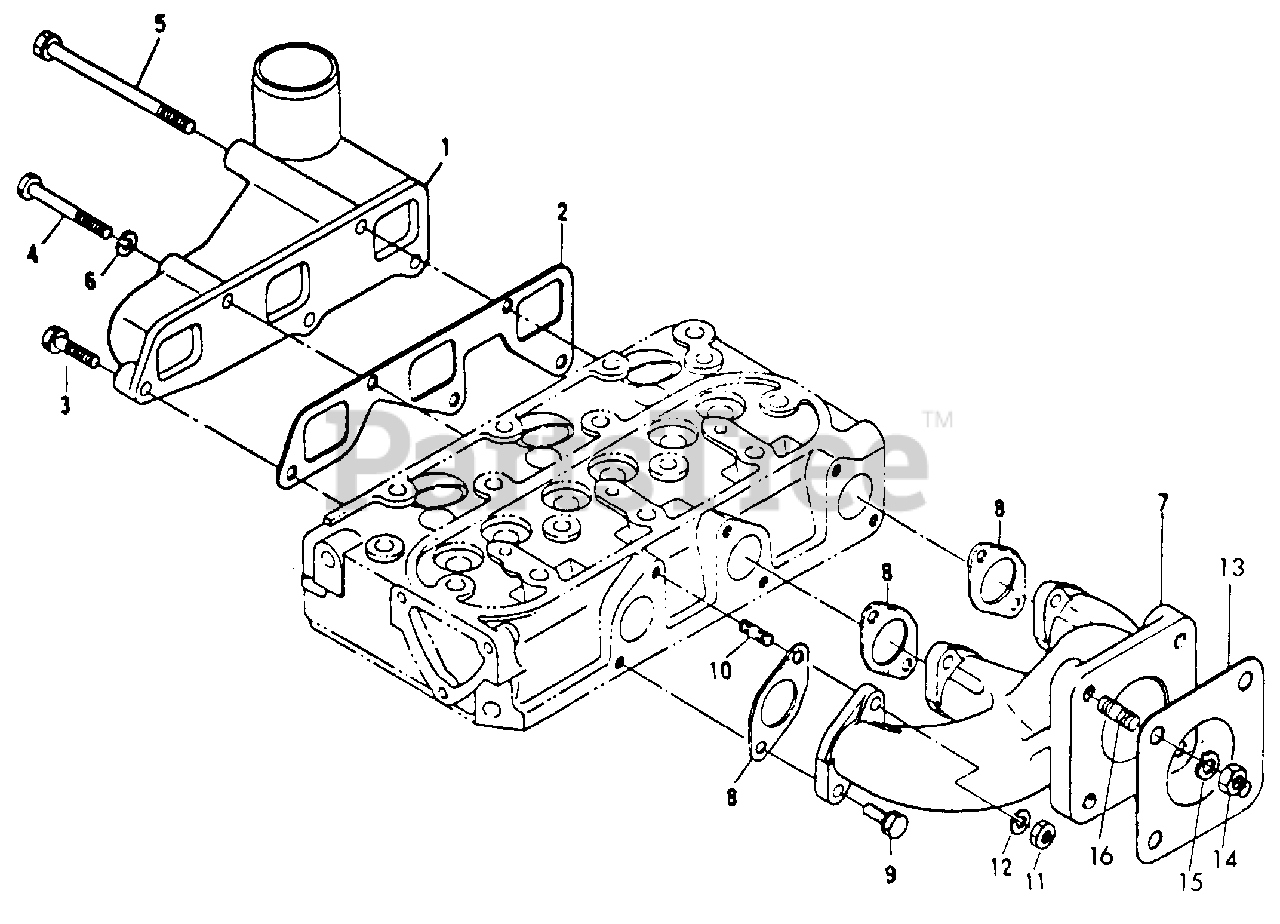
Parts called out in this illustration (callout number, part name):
1	Manifold, Inlet
2	Gasket, Inlet Manifold
3	Bolt, M6 X 25 Class 8.8
4	Bolt, M6 X 50MM Class 8.8
6	Washer, 6MM Lock
7	Manifold, Exhaust
8	Gasket, Exhaust Manifold
9	Bolt, M6 X 18-8.8
11	Nut, M6 Znd Class 8
12	Washer, 6MM Lock
13	Gasket
14	Nut, M8 Class 8
15	Washer, 8MM Lock
